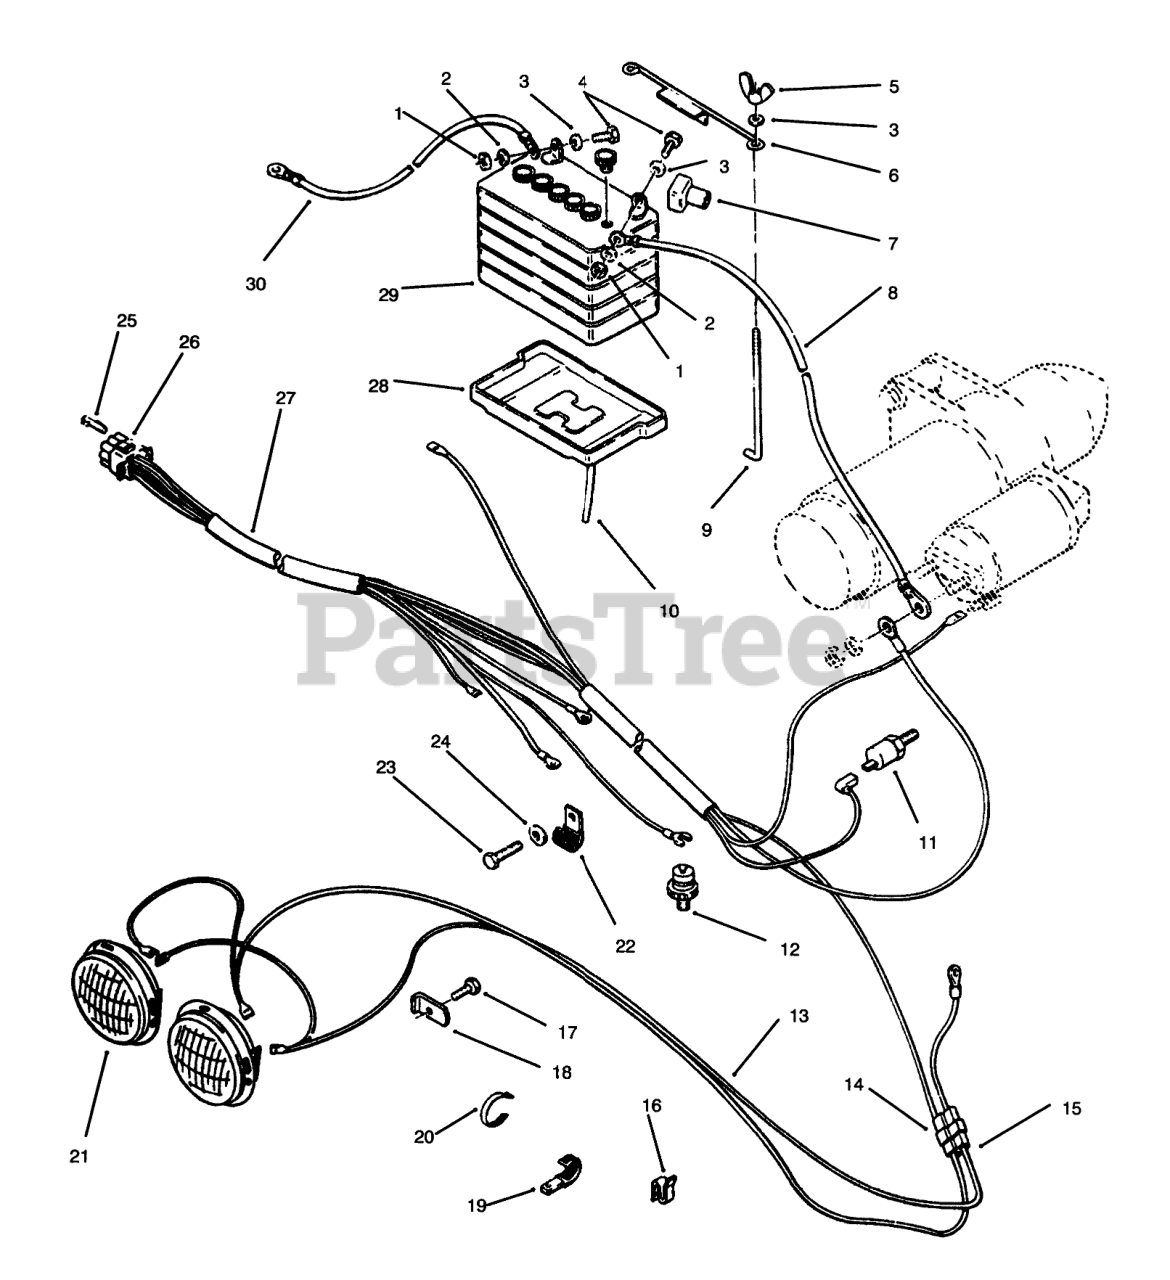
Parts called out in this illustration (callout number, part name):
1	NUT-LOCK, NI
2	WASHER-LOCK
3	WASHER-FLAT
4	SCREW-HH
5	NUT-WING
6	HOLDDOWN-BATTERY
7	Boot
8	ASS'Y-WIRE
9	HOOK-BATTERY RETAIN
10	TUBE-21" BATTERY DRAIN
11	HIGH TEMPERATURE
12	SWITCH - OIL PRESSURE
13	HARNESS-HEADLIGHT
14	MALE CONNECTOR
15	CONNECTOR BODY
16	SPEED CLIP
17	Bolt
18	LOCK-HEADLIGHT
19	CLIP
20	PLASTIC TIE
21	HEADLAMP
22	CLIP-WIRE
23	SCREW-HWH
24	LOCKWASHER 1/4 IT
25	CONTACT SOCKET
26	CONNECTOR CAP
27	HARNESS - ENGINE WIRE
28	THRUST WASHER
29	Battery
30	ASS'Y-WIRE
